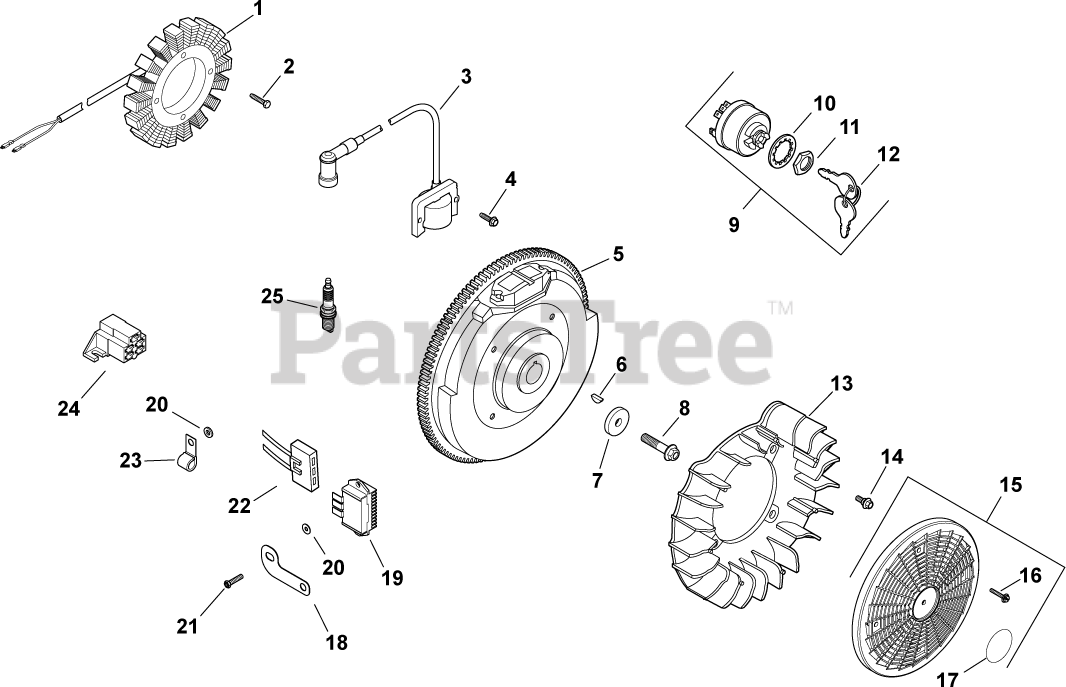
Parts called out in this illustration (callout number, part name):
1	KIT, 15 / 20 AMP STATOR
2	SCREW, M5X0.8X25 - (#25086402S)
3	MODULE, IGNITION
4	SCREW, FLG THD FRM M5X.8X20-(#25086399S)
5	FLYWHEEL ASSEMBLY (LW)
6	KEY, 3/16" X 5/8"
7	WASHER, FLAT 13/32"
8	SCREW, FLG M10X1.5X45 - (#25086361S)
9	SWITCH ASSY, KEY (KM)-USE 25 099 32-S
10	WASHER, INTERNAL TOOTH
11	NUT, KEY SWITCH
12	KEY, SET -USE 48 340 01-S
13	FAN USE 24 755 253-S
14	BOLT, SHOULDER
15	KIT, GRASS SCREEN
16	SCREW, FLG SEMS M4X.7X25
17	DECAL, GRASS SCREEN USE 24 113 499-S
18	BRACKET, GROUND STRAP USE 24 518 12-S
19	REG/RECT-15 AMP (KM)-USE 41 403 10-S
20	WASHER, FLAT 1/4" (O.D. 1/2")
21	SCREW, HEX FLANGE HI-LO
22	CONNECTOR, BODY (KM)-USE 25 155 41-S
23	CLIP, CABLE
24	CONNECTOR
25	PLUG, SPARK (PRO SERIES)
2451809-S	LEAD, OIL SENTRY
2458452-S	MODULE, SPARK ADV -USE 24 584 89-S
